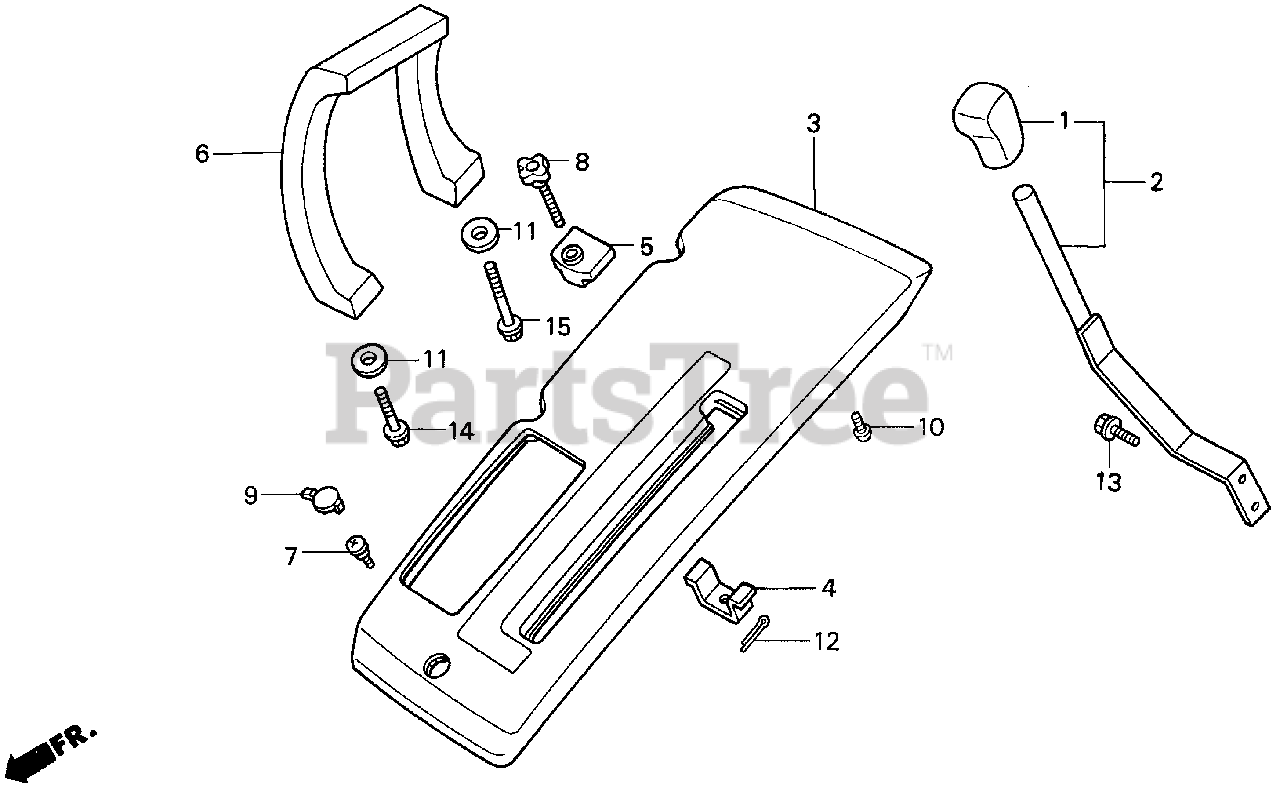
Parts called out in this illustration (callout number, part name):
1	KNOB, P.T.O. CHANGE LEVER
2	LEVER, POSITION CONTROL
3	PANEL, R. CONTROL *NH247* (ASSEMBLY GRAY)
4	PLATE, STOPPER SETTING
5	STOPPER, POSITION LEVER
6	GRIP, R. *NH247* (ASSEMBLY GRAY)
7	SCREW, VISOR SPECIAL SETTING
8	BOLT, STOPPER
9	CAP, LINING *NH120L* (STAR BLACK)
9	CAP, LINING *NH1L* (BLACK)
10	SCREW, PAN (5X8)
11	WASHER, PLAIN (8MM)
12	PIN, COTTER (1.0X12)
13	BOLT, FLANGE (8X14)
14	BOLT, FLANGE (8X38)
15	BOLT, FLANGE (8X55)
